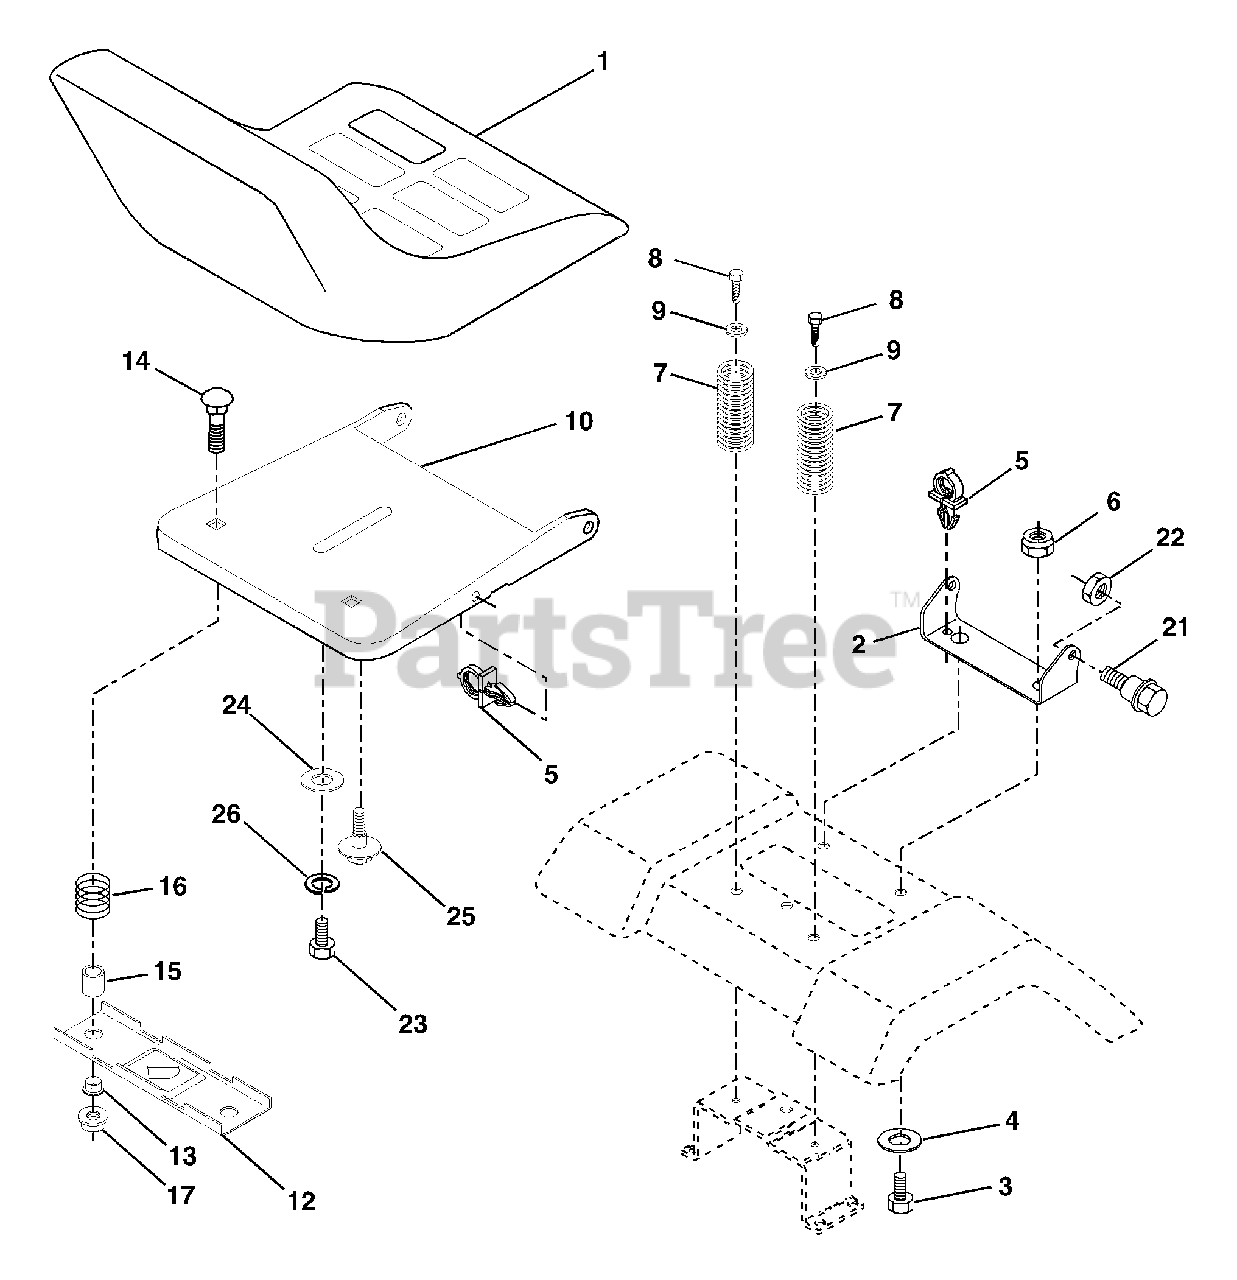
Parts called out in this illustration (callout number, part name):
1	Seat
2	Bracket Pivot Seat 8 720
3	Bolt Fin Hex 3/8-16 unc x 1
4	Washer 13/32 x 1 x 10 Ga.
5	Clip Push-In
6	Nut Hex w/Ins. 3/8-16 unc
7	Spring Seat Cprsn 2 250 Blk Zi
8	Screw 3/8-16 x 1
9	Washer 13/32 x 1 x 14 Ga.
10	Pan Seat
12	Bracket Mounting Switch
13	Bushing Snap Blk Nyl 50 Id
14	Bolt Rdhd Sqnk 1/4-20 x 1-1/2
15	Spacer Split 28 x 96 Yel Zinc
16	Spring Cprsn 1 27 Blk Pnt
17	Nut Lock 1/4 Lge Flg Gr. 5 Zinc
21	Bolt Shoulder 5/16-18 unc-2A
22	Nut Hex Lock W/Ins 5/16-18
23	Bolt, Hex Black
24	Washer 17/32 x 1-3/16 x 12 Ga.
25	Bolt Shoulder 5/16-18 x 62
26	Washer Lock
